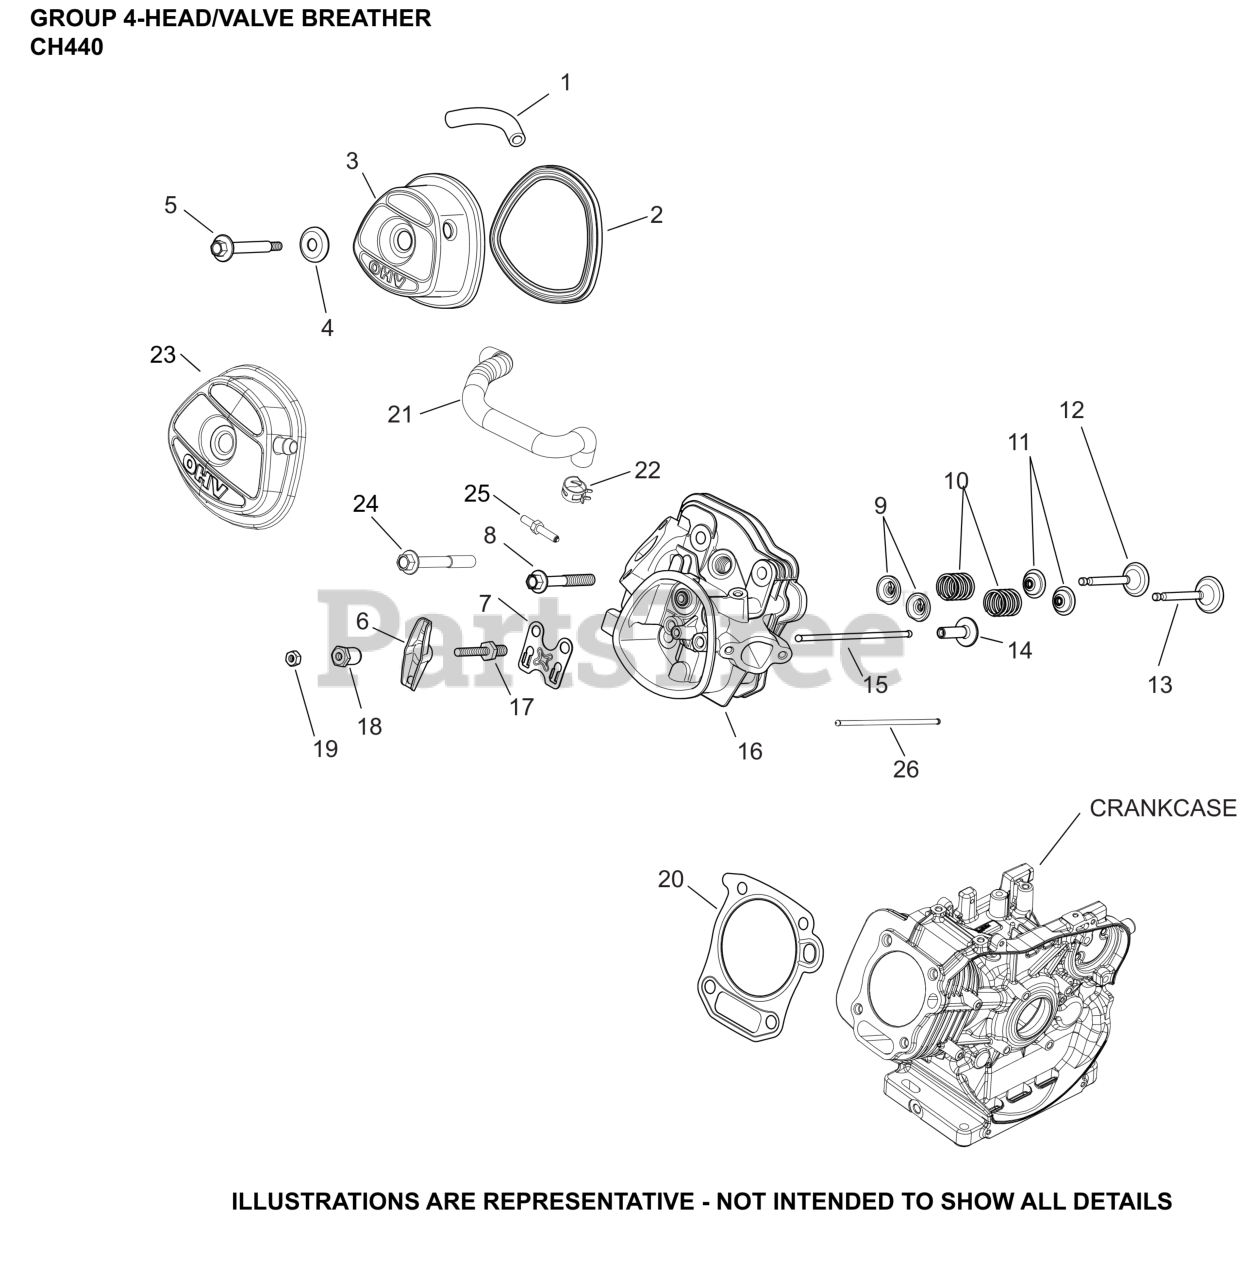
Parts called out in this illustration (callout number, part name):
1	TUBE, BREATHER
2	GASKET, VALVE COVER
3	KIT, VALVE COVER ASSEMBLY
5	SCREW, VALVE COVER SEAL ASSY
6	ARM, ROCKER
7	PLATE, PUSHROD GUIDE
8	SCREW, HEX FLANGE CYLINDER HEAD
9	RETAINER, VALVE SPRING
10	SPRING, VALVE
11	SEAL, VALVE STEM
12	VALVE, EXHAUST
13	VALVE, INTAKE
14	LIFTER, VALVE
15	ROD, PUSH-(#1741110S)
16	KIT, HEAD ASSY
17	STUD, ROCKER ARM-USE 14 072 22-S
18	PIVOT, ROCKER ARM
19	NUT, HEX JAM
20	KIT, HEAD GASKET
